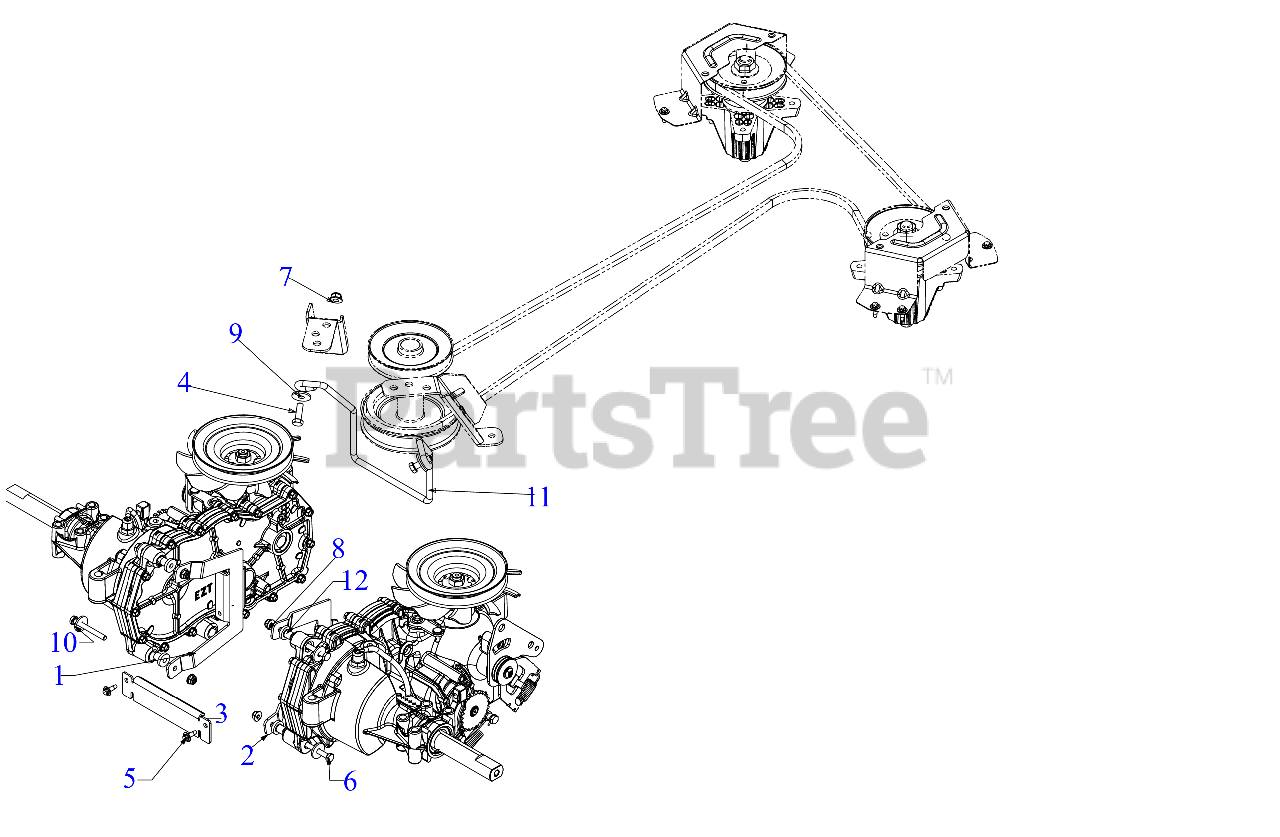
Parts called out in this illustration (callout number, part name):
4	SCREW 5/16-18 x 1.0 GR5
5	SCREW M6-1 x .625
6	SCREW 1/4-20 x 2.25 GR5
7	FLANGE LOCK NUT 5/16-18
8	FLANGE LOCK NUT
9	FLAT WASHER 1.0 OD:.331 ID
10	FLAT WASHER
11	BELT KEEPER ROD
12	STEP SPACER
